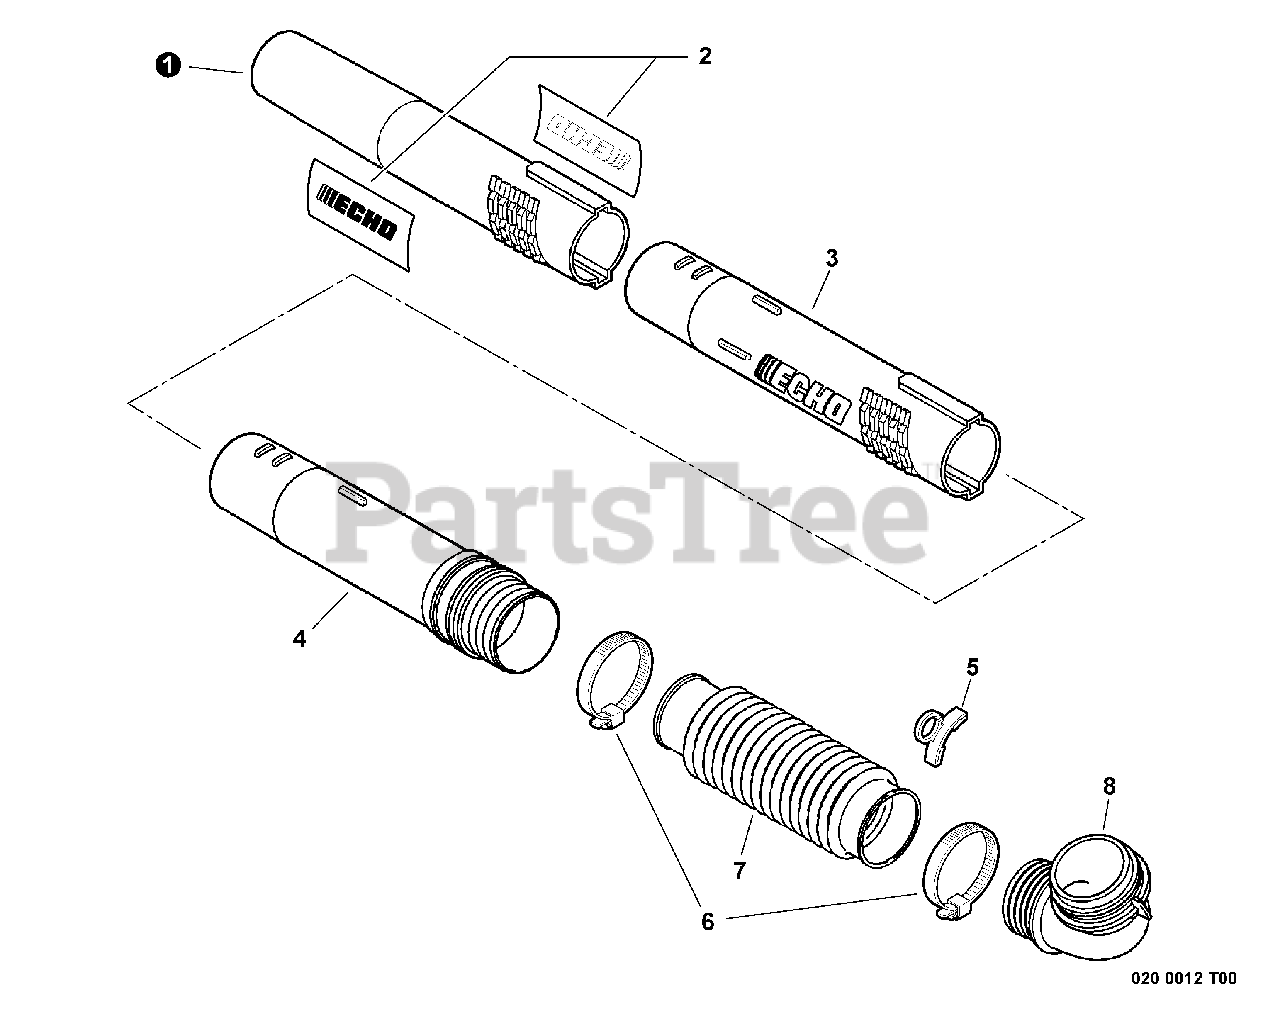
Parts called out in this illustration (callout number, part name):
1	TUBE, BLOWER - STRAIGHT NOZZLE
2	LABEL - ECHO
3	TUBE, BLOWER - STRAIGHT
4	TUBE, BLOWER - SWIVEL
5	CLIP, CABLE
6	CLAMP, HOSE
7	TUBE, BLOWER - FLEXIBLE
8	TUBE, BLOWER - ELBOW
